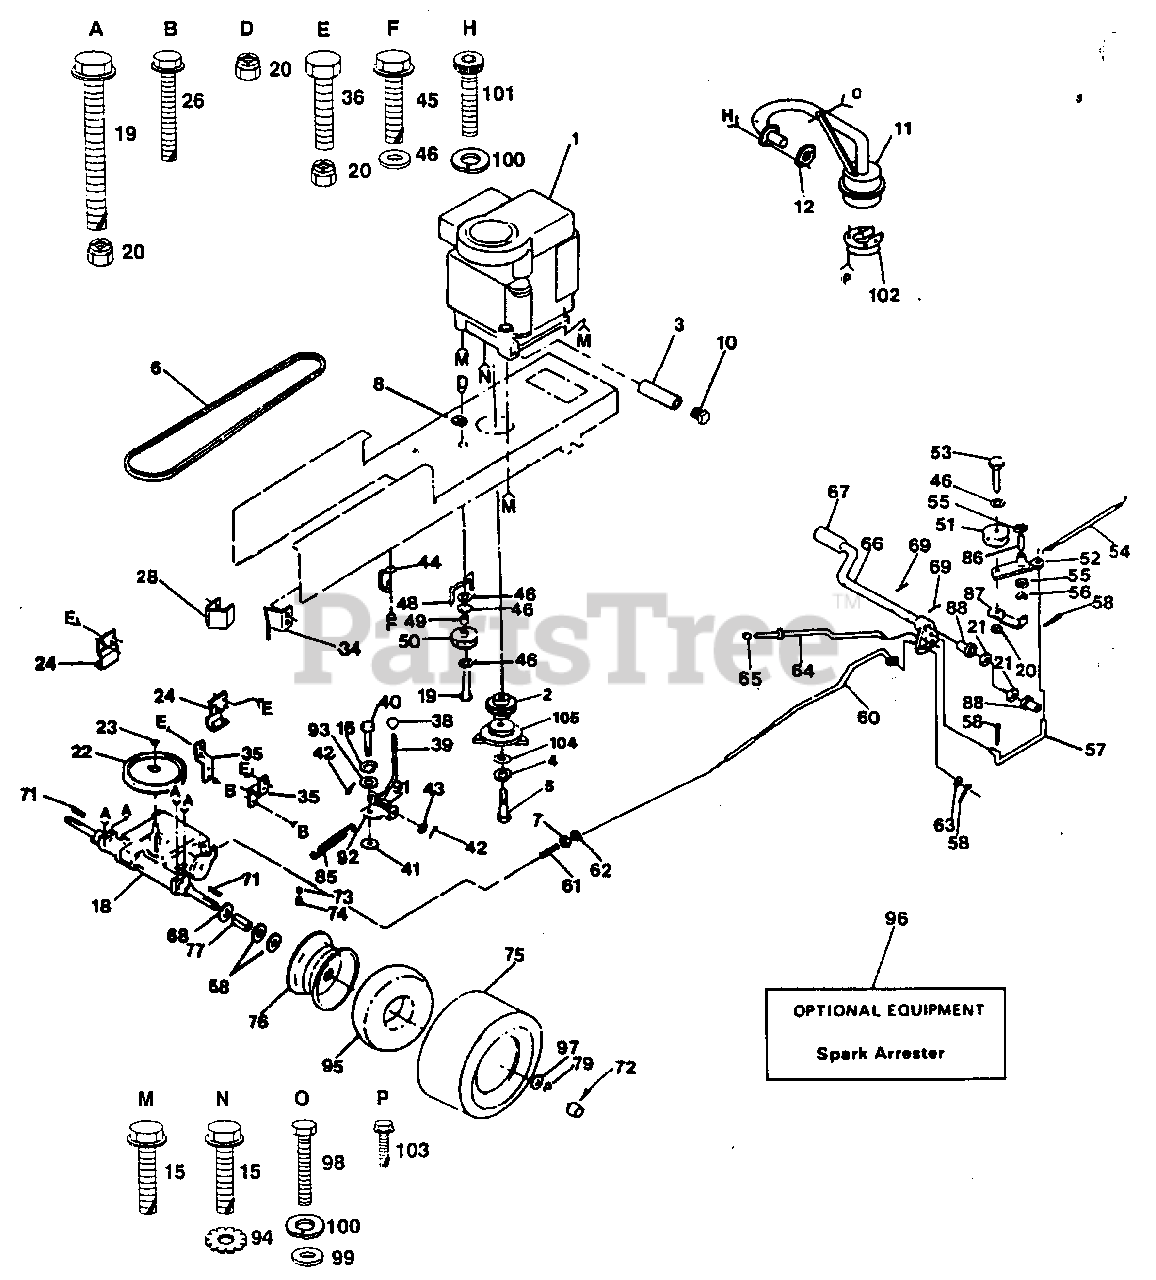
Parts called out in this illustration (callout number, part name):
1	Engine 12 HP, Briggs & Stratton Model No. 281707, Type No. 0413-01
2	Pulley, Engine
3	Pipe, Drain, Oil
4	Washer, Lock 7/16
5	Bolt, Hex 7/16-20 x 1-1/4
6	V-Belt, Drive
7	Locknut, Hex 3/8-16 UNC ZN
8	Clip, Fuel Line
12	Gasket
15	Screw, Hex Washer Thread Rolling 3/8-16 x 1-1/4
16	Washer, Lock 1/4
18	Transaxle Foote, 6 Speed, Model No. 4360-7
19	Bolt, Hex 3/8-16 x 2-3/4
20	Nut, Crownlock 3/8-16
21	Washer 21/32 x 1 x 16 Ga
22	Pulley, Transaxle
23	Ring, Retainer
24	Bracket, Transaxle
26	Screw, Hex Washer Thread Rolling 5/16-18 x 3/4
28	Keeper, Belt, L.H.
34	Keeper, Belt, R.H.
35	Strap, Torque, Transaxle
36	Bolt, Hex 3/8-16 x 3/4
40	Bolt, Shift Plate
41	Washer, Shift Plate
42	Pin, Cotter 1/8 x 1
43	Washer 15/32 x 3/4 x 16 Ga.
44	Belt, Retainer
45	Screw, Hex., Washer Thread Rolling 3/8-16 x 3/4
46	Washer 13/32 x 13/16 x 12 Ga.
48	Retainer, Belt
49	Spacer
51	Pulley, Idler
53	Bolt, Hex. 3/8-16 x 1-1/2
54	Spring, Return Clutch
55	Washer, Hardened
57	Link, Clutch
58	Pin, Cotter 1/8 x 3/4
60	Rod, Brake
61	Spring, Rod, Brake
62	Nut, Jam 3/8-16
63	Washer 13/32 x 13/16 x 16 Ga.
64	Rod, Brake, Parking
66	Shaft, Foot Pedal
67	Cover, Pedal
68	Washer 25/32 x 1-1/4 x 16
69	Pin, Roll 3/16 x 1
71	Key, Square 2.5 x .1845/.1865
76	Rim Assembly, Rear
85	Spring, Brake
87	Retainer, Belt
88	Bearing, Nylon
93	Washer 9/32 x 3/4 x 10 Ga.
94	Washer, Lock, External Tooth 3/8
95	Tube, Tire
96	Spark Arrester
97	Washer 25/32 x 1-5/8 x 16 Ga.
98	Bolt, Hex Fin 1/4 x 20 UNC x 1
99	Washer 9/32 x 5/8 x 16 Ga.
100	Washer, Lock, Heavy Helical Spring
101	Screw, Hex Head Cap 5/16-18 x 5/8
102	Deflector, Muffler
103	Screw, Spiderlock, Hex Head #8 x 1/2 AB
104	Washer 1-1/2 x 15/32 x 1/4
105	Clutch, Electric
